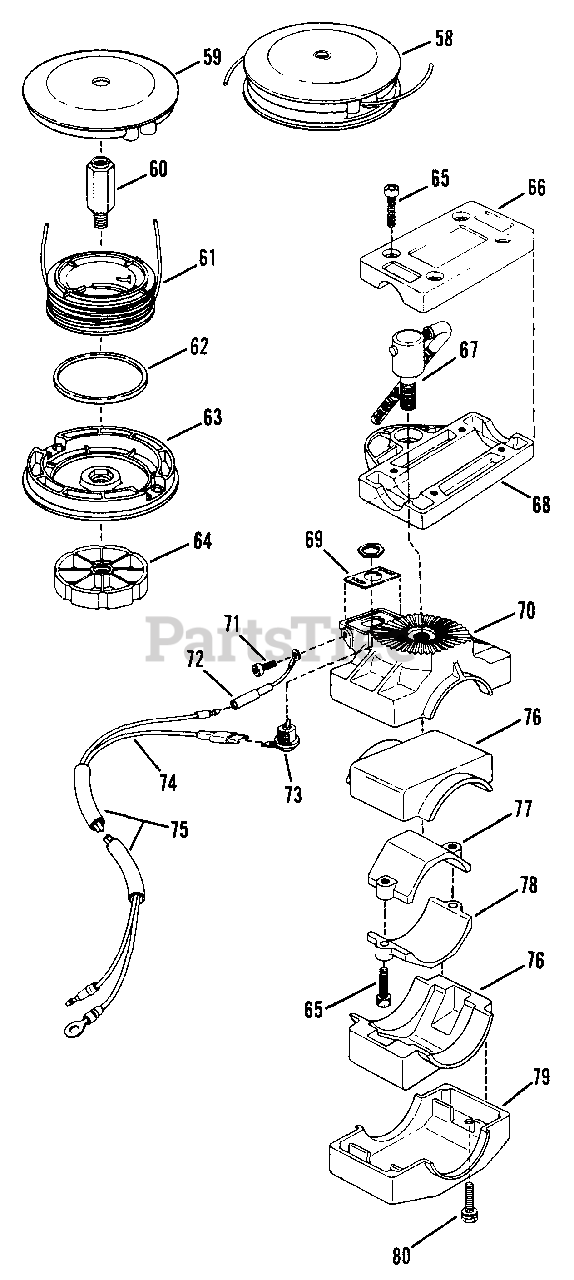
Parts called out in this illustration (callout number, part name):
58	MANUAL HEAD ASSM'Y.
59	HOUSING, Upper
60	ARBOR (10mm threads)
61	SPOOL & LINE
63	HOUSING, Lower
64	KNOB, Lock
65	SCREW, M5 x 20mm, Allen Hd.
66	JOINT "A", Handle
67	LOCK HANDLE
68	JOINT "B", Handle
69	PLATE, Switch
70	JOINT "D", Handle
71	SCREW, M5 x 10mm
72	LEAD, Wire (Ground)
73	SWITCH, Stop
74	WIRE LEADS
75	TUBE, Wire Leads
76	RUBBER, Vibro
77	FITTING "B", Tube
78	FITTING "A", Tube
79	JOINT "C", Handle
80	BOLT, M6 x 30mm, Hex
